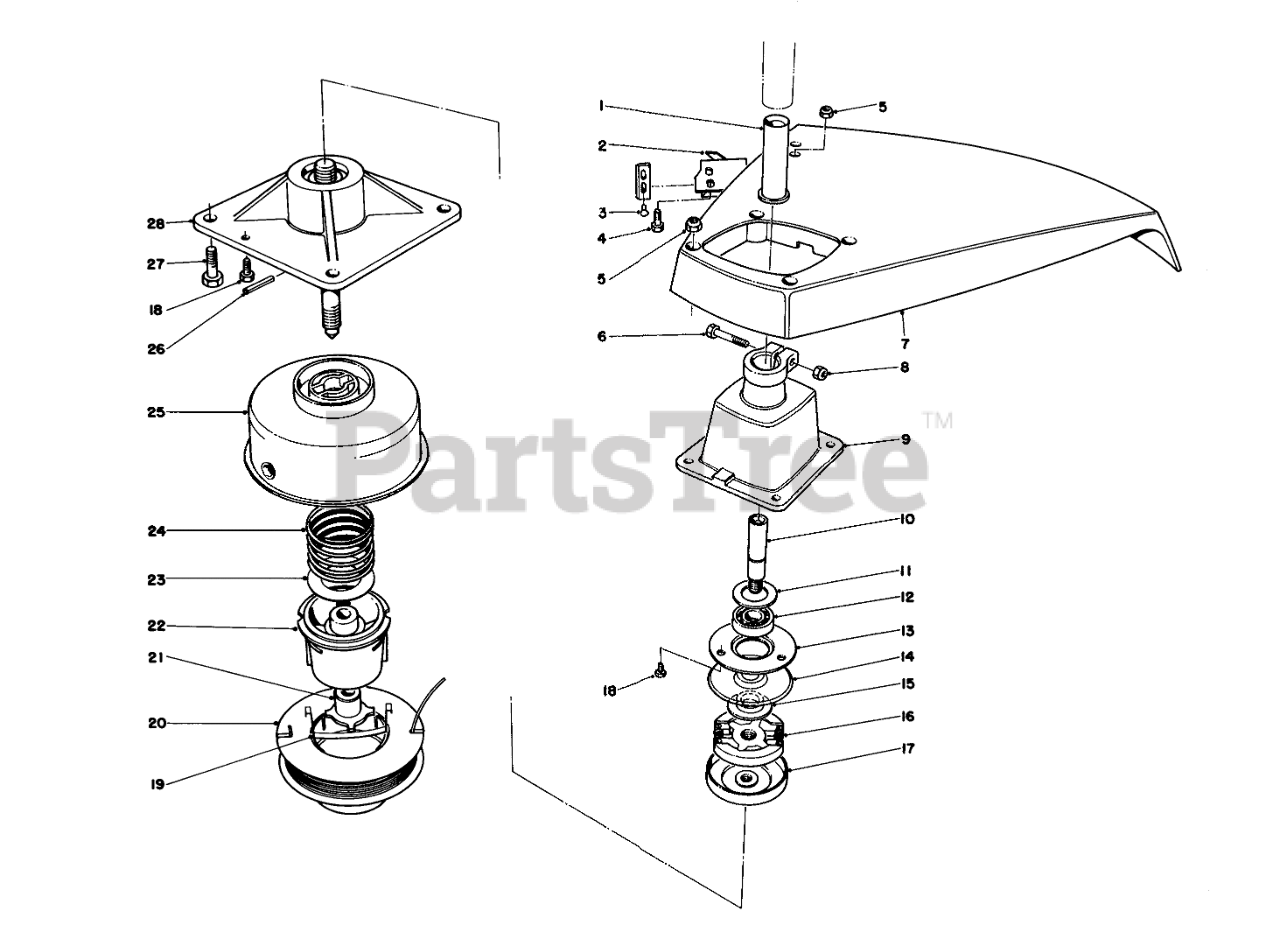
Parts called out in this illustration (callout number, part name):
1	INSERT-POLE END
2	Bracket & Knife Blade Assy. (Incl. Rf. #3)
3	RIVET-BLIND
4	SCREW-HWH
5	NUT-LOCK, NI
6	SCREW-HH
7	Shield 17"
9	Clutch Housing Assembly (Incl. Ref. #6 & 8)
10	SHAFT-UPPER POWER
11	Washer-Flat
12	Bearing
13	Retainer-Bearing
14	CLUTCH SHIELD-WILLMAR
15	Spacer-Clutch
16	Clutch Assembly
17	Drum Assembly
18	SCREW-TAPTITE
19	SADDLE-SPOOL CAP
20	Prewound Spool (.080)
21	DRIVER
22	SPOOL CORE
23	Washer
24	SPRING COMPRESSION
25	DRUM/EYELET
26	COIL PIN
27	10-24 X 7/8 IND HD SC
28	Bearing Housing Assembly
